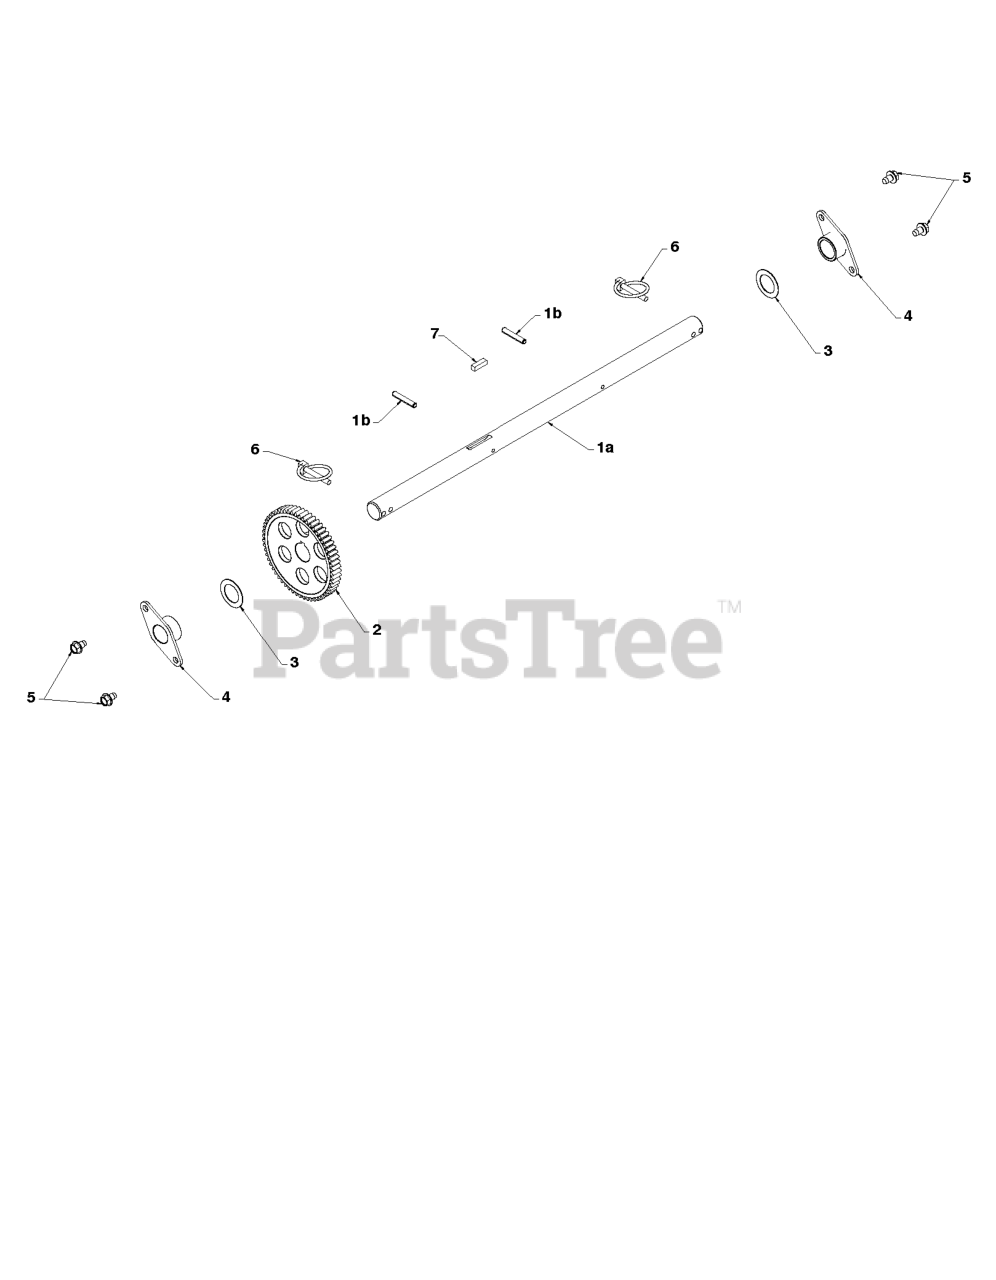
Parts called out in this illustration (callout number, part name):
1	AXLE.SHAFT.ASM.W/ROLPIN.NON-PS
2	GEAR, AXLE (58T)
3	WASHER TRUST 1"
4	BEARING, AXLE
5	Screw 5/16-18 x 1/2 Hex, Self Tapping 5/16-18 x 1/2
6	PIN KLIK, 1/4
7	KEY, SQUARE 1/4 X .875
